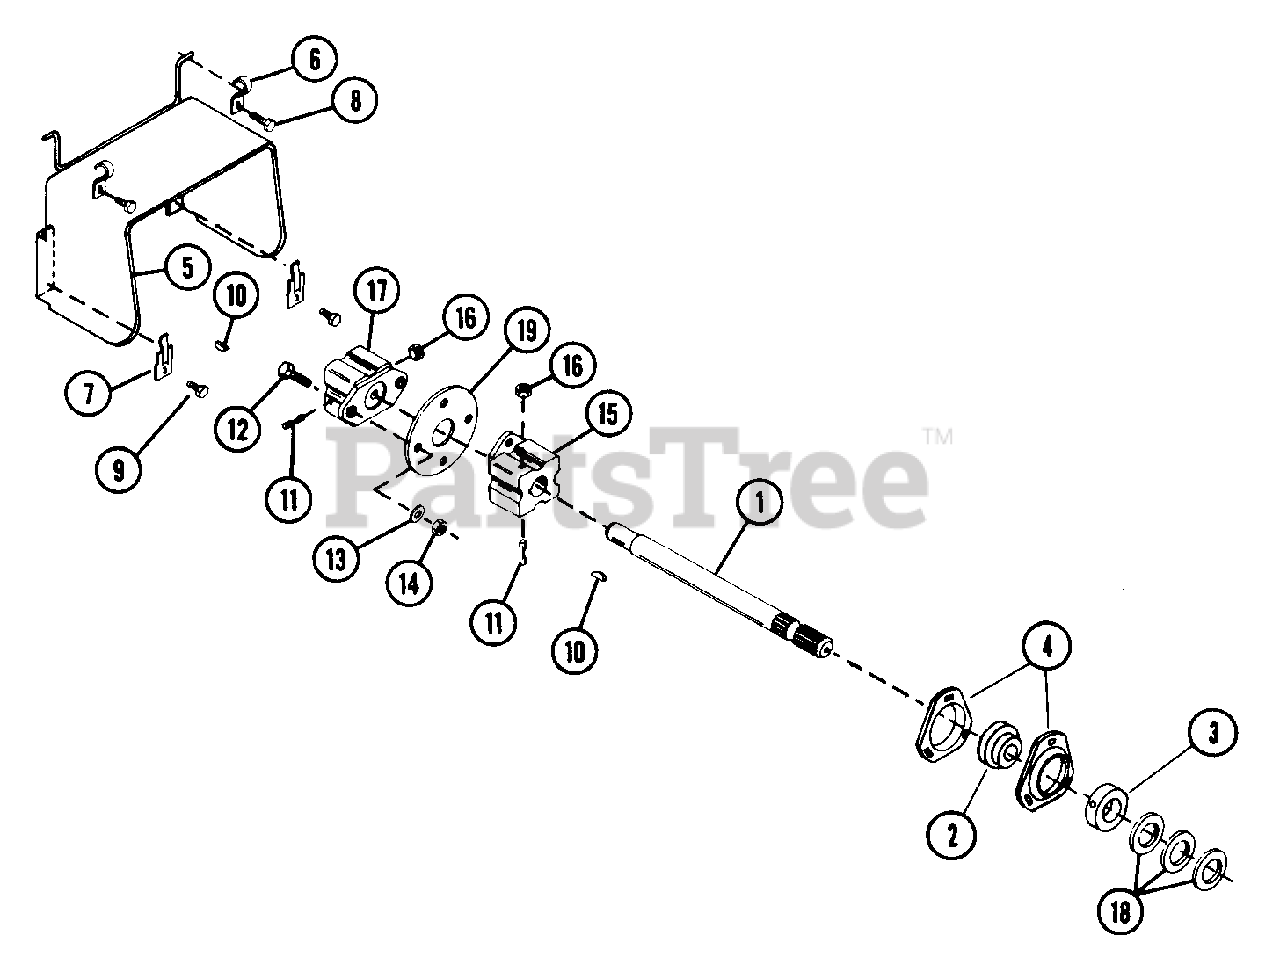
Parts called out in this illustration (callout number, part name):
1	REAR PTO SHAFT
2	BRG/W COLLAR 1.0 X 2.047 X.844
3	BEARING COLLAR
4	BEARING FLANGE
5	PTO SHIELD
7	SNAP FASTENER
8	SCR-TAP .250-20X.50 HXSLHDPL
9	SCR-TAP 10-24X.375 HWH PL TR
10	KEY-WDRF .188X.75X.313 SAE 9
11	LOCK STUD
12	BLT-HEX .31-18X.75 PL GR2
13	WSHR-FL-STL.344X.688X.065PL
14	NUT-LK .312-18 GR A PL
15	DRIVE HUB
16	NUT-LK TOP .375-16 GR C YWZC
17	DRIVE HUB - HYDRO
18	SPACER-SPECIAL CONICAL
19	SPACER COUPLING
